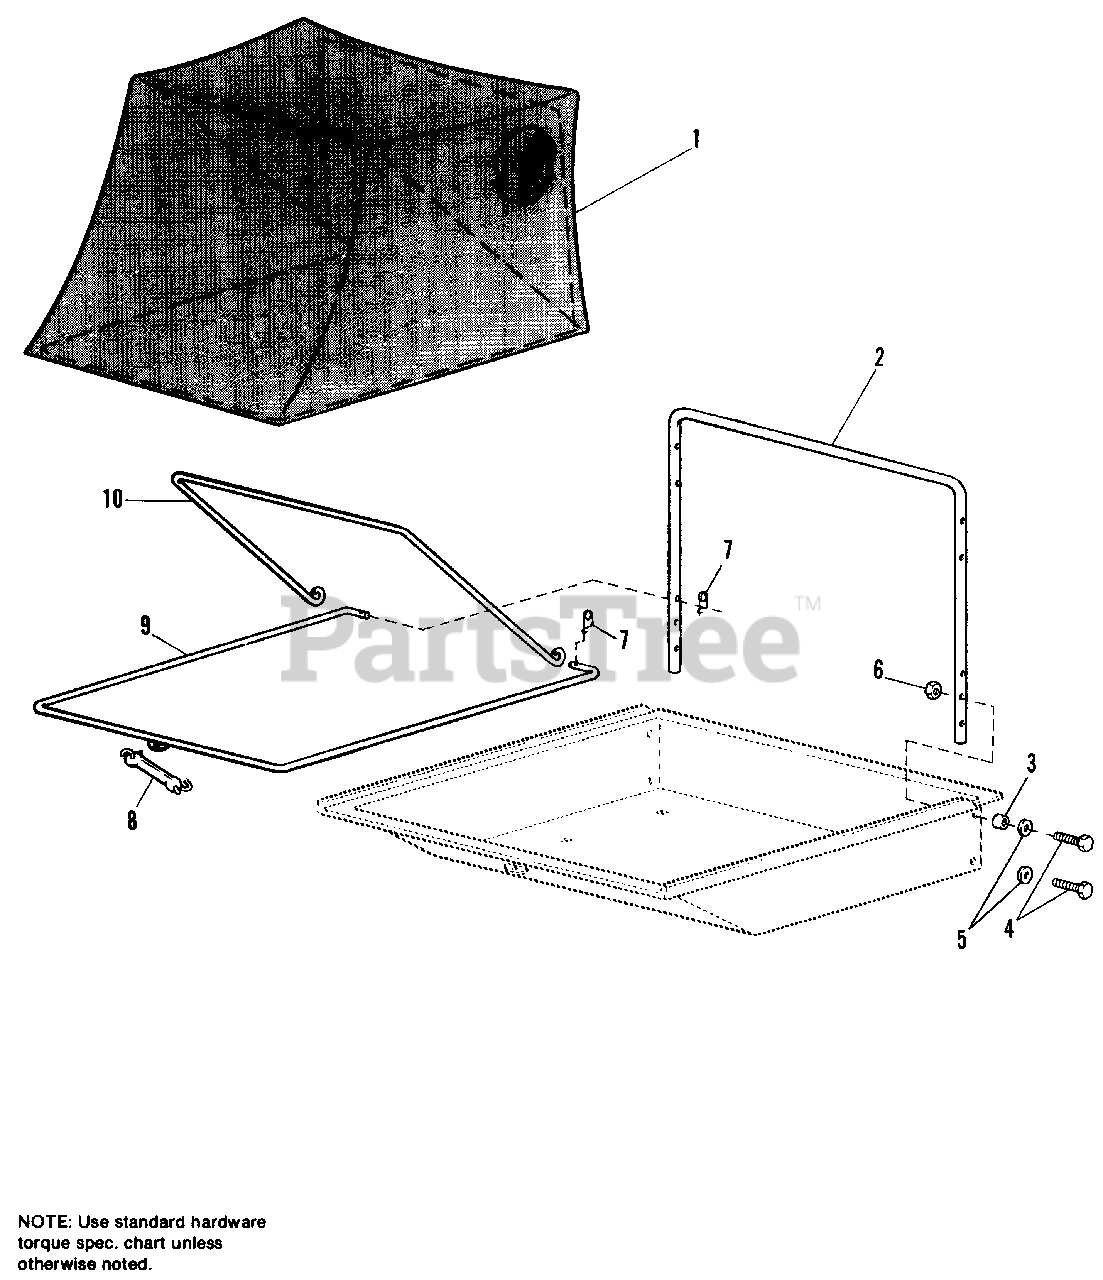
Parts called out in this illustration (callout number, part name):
2	TUBE, Support
3	SPACER, Plastic
4	CAPSCREW, 5/16-18 x 1-1/2
5	WASHER, 5/16
6	NUT,Lock, 5/16-18
7	COTTER,Hairpin
8	STRAP, Rubber
9	ROD, Frame
10	ROD, Support
